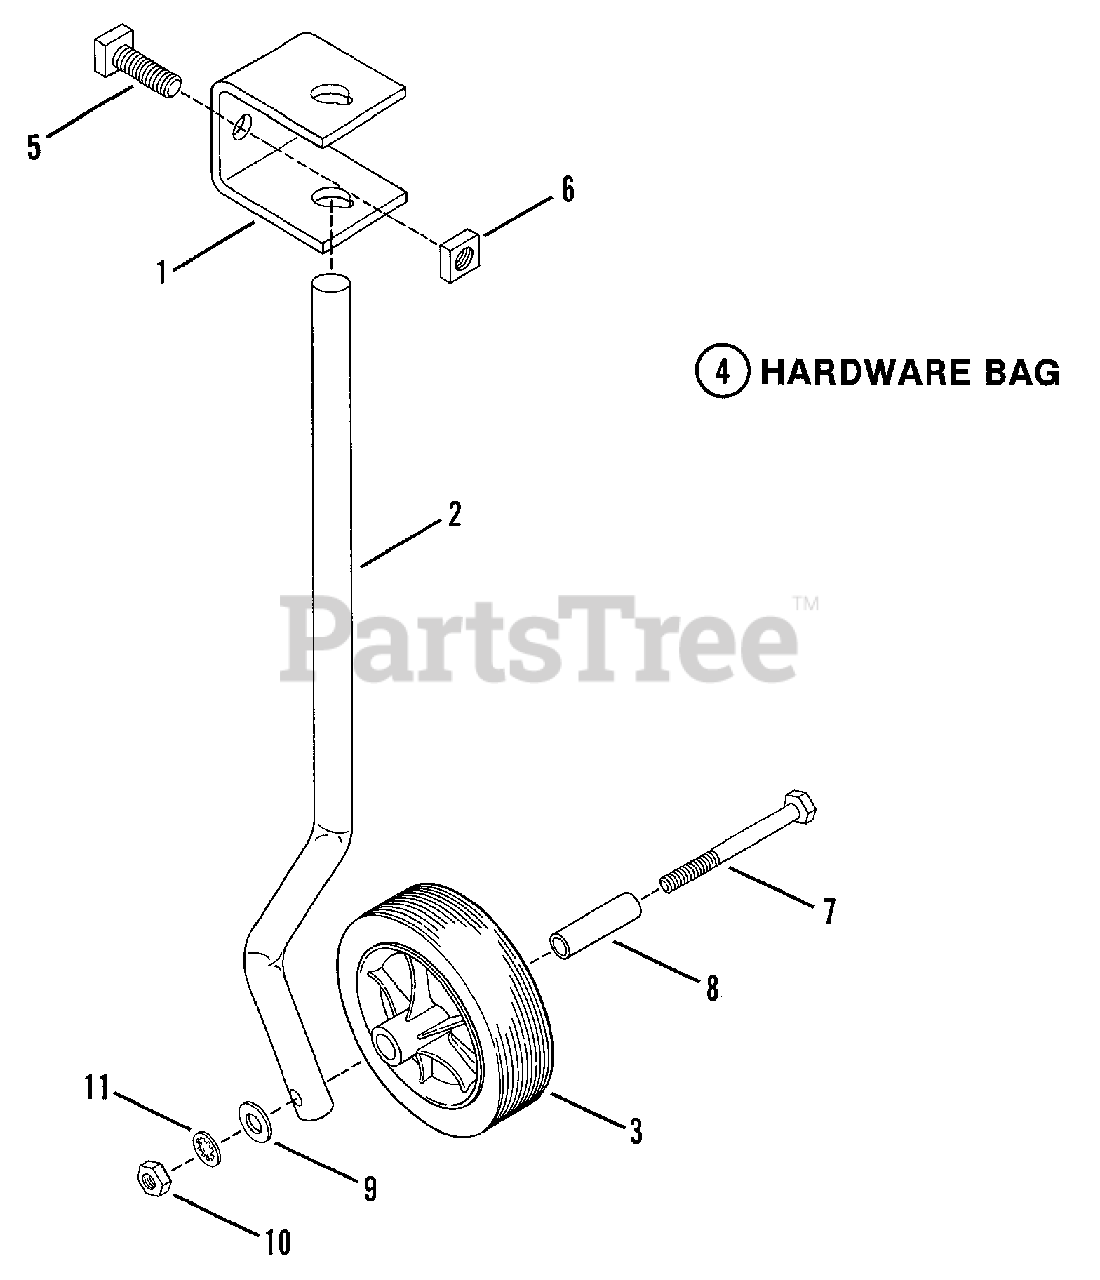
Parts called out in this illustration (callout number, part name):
1	CLAMP
2	(NLA) SHANK, Gauge Wheel
5	SCREW, 1/2-13 x 1-1/4"
6	NUT, 1/2-13 Square
7	SCREW, 3/8-24 x 3.75" Hex Head Cap
8	BUSHING, Axle
9	WASHER, 3/8" Flat
10	NUT, 3/8-24 Hex, Grade 2
11	WASHER, 3/8 Internal Tooth Lock
